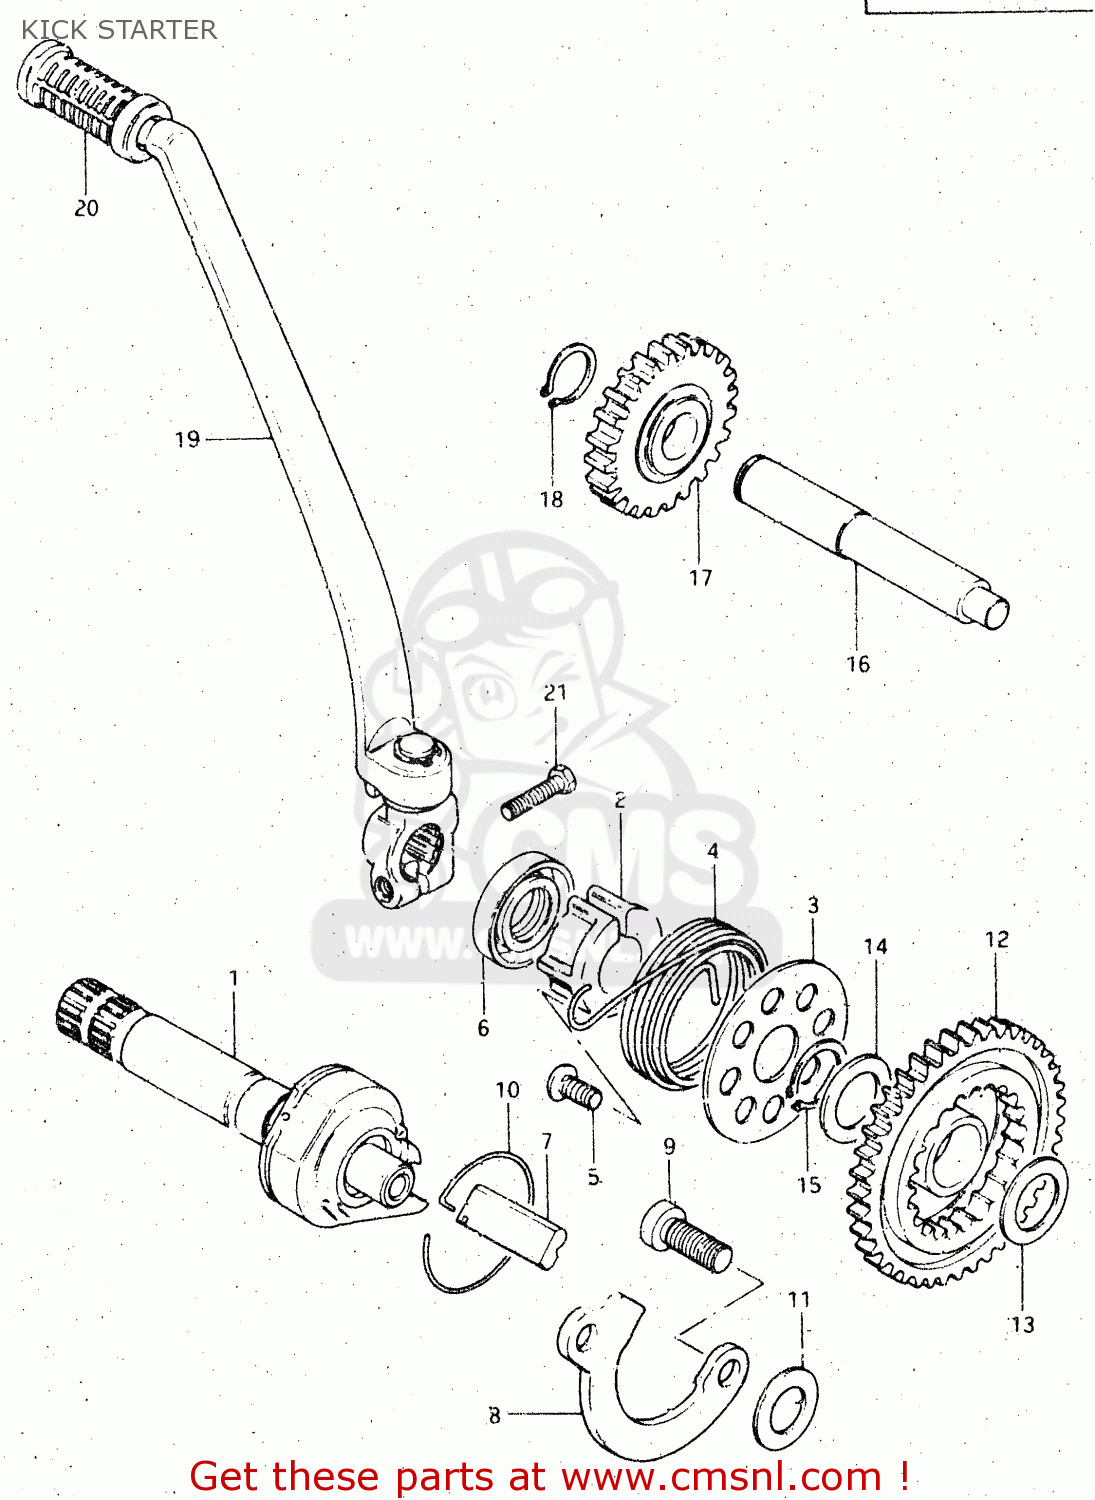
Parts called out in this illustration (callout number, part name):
1	SHAFT,KICK STARTER
2	GUIDE,KICK SHAFT SPRING
3	HOLDER,KICK SHAFT SPRING
4	SPRING
5	SCREW
6	SEAL,OIL(20X37X7)
7	PAWL,KICK STARTER
8	LIFTER,KICK STARTER
9	STOPPER,KICK STARTER
10	SPRING,KICK START PAWL RETURN
11	WASHER
12	GEAR,KICK STARTER DRIIVE
13	WASHER
14	WASHER,THRUST
15	CIRCLIP
16	SHAFT,KICK STARTER IDLE
17	GEAR,KICK STARTER IDLE
18	CIRCLIP
19	LEVER ASSEMBLY,KICK STARTER
20	RUBBER,KICK STARTER PEDAL
21	BOLT 8X25
